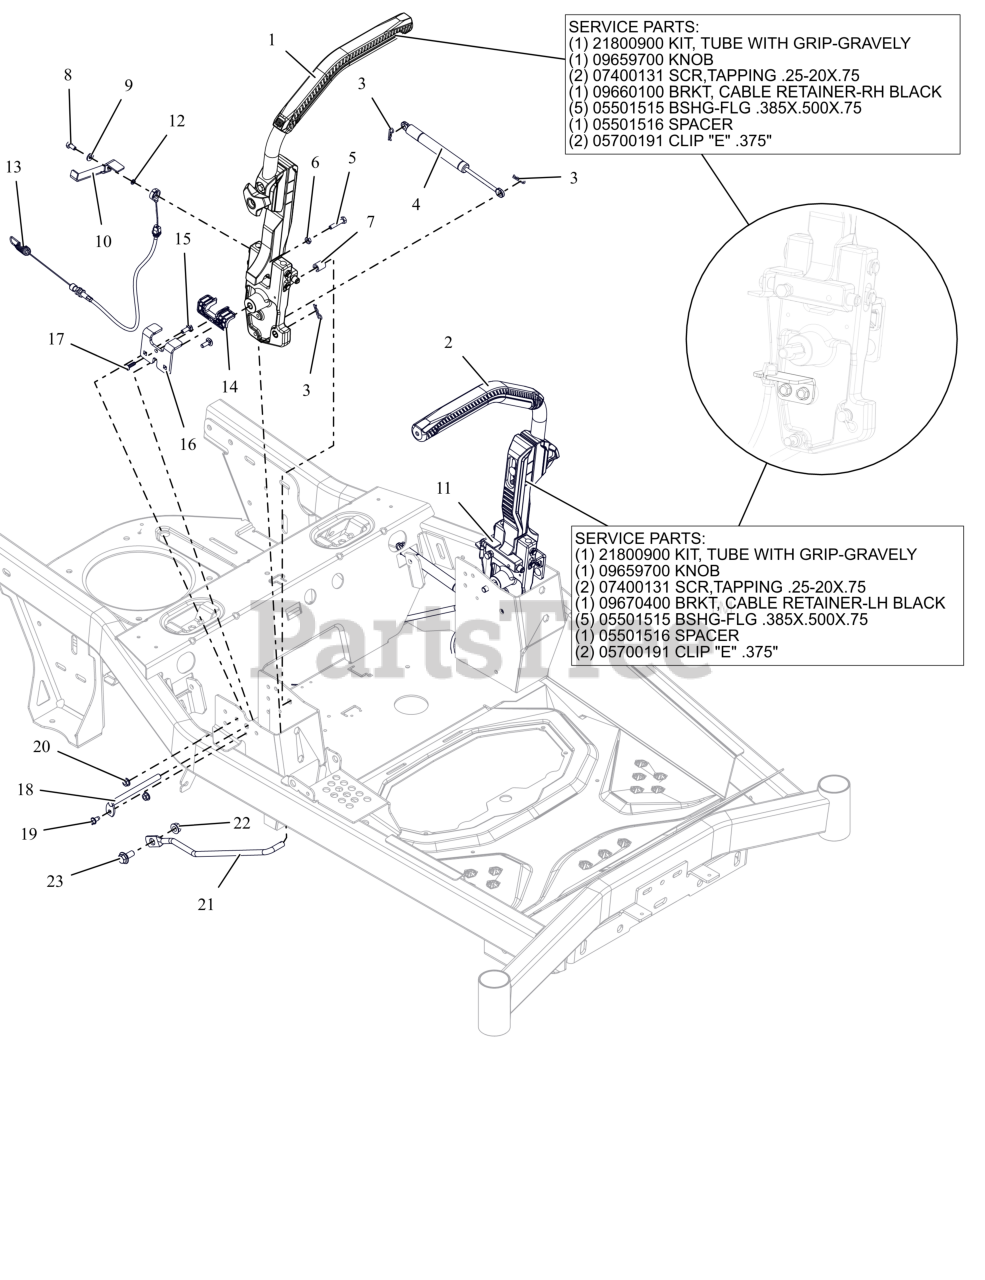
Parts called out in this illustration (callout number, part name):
1	ASM- CONTROLS -RH-GRAVELY
1	KIT, TUBE WITH GRIP-GRAVELY
1	KNOB- STEERING ADJUSTMENT
1	SCR,TAP .25-20X.75 HWH TR ZCC
1	BRKT- CABLE RETAINER
1	BSHG-FLG .385X.500X.75
1	SPACER SLEEVED .385X.500X1.045
1	3/8" E RETAINING RING EXTERNAL
2	ASM- CONTROLS -LH -GRAVELY
2	KIT, TUBE WITH GRIP-GRAVELY
2	KNOB- STEERING ADJUSTMENT
2	SCR,TAP .25-20X.75 HWH TR ZCC
2	BRKT5- CABLE RETAINER LH-BLK
2	BSHG-FLG .385X.500X.75
2	SPACER SLEEVED .385X.500X1.045
2	3/8" E RETAINING RING EXTERNAL
3	PIN, HAIR #213 .08X1.19 ZCC
4	DAMPER- STRAIGHT MOUNT
5	BLT, HEX 0.25-20X1.25F GR5 ZCC
6	NUT-JAM .250-20 G2 ZCC
7	SPCR- SNAP-ON 1/2 X 1 1/2
8	BLT, HEX 0.375-16X1 GR5 EP80 ZC120
9	WSHR,FLT .281X.625X.065 ZCC
10	BRKT, PARKING BRK ENG R (BLACK)
11	BRKT- PARKING BRK ENG R-BLACK
12	WSHR-FLT .250X.406X.050 ZCC
13	CABLE- PARK BRAKE
14	STEERING, PLASTIC LINER
15	BLT, RHSN .25-20X.750 G5 ZCC
16	PLATE- BRAKE STOP
17	SCR-TAP 12-14X.75PLSTITE @BLZC
18	PIN- FIXED STEERING PIVOT
19	SCR-TAP .25-20X.50 HWH ZCC
20	NUT-LK-CTR-FLG .25-20 ZC120
21	WIREFORM- STEERING LINKAGE
22	NUT-LK-CTR-FLG .375-16 GF ZCC
23	BLT- SHLDR .375-16X.100X.72
